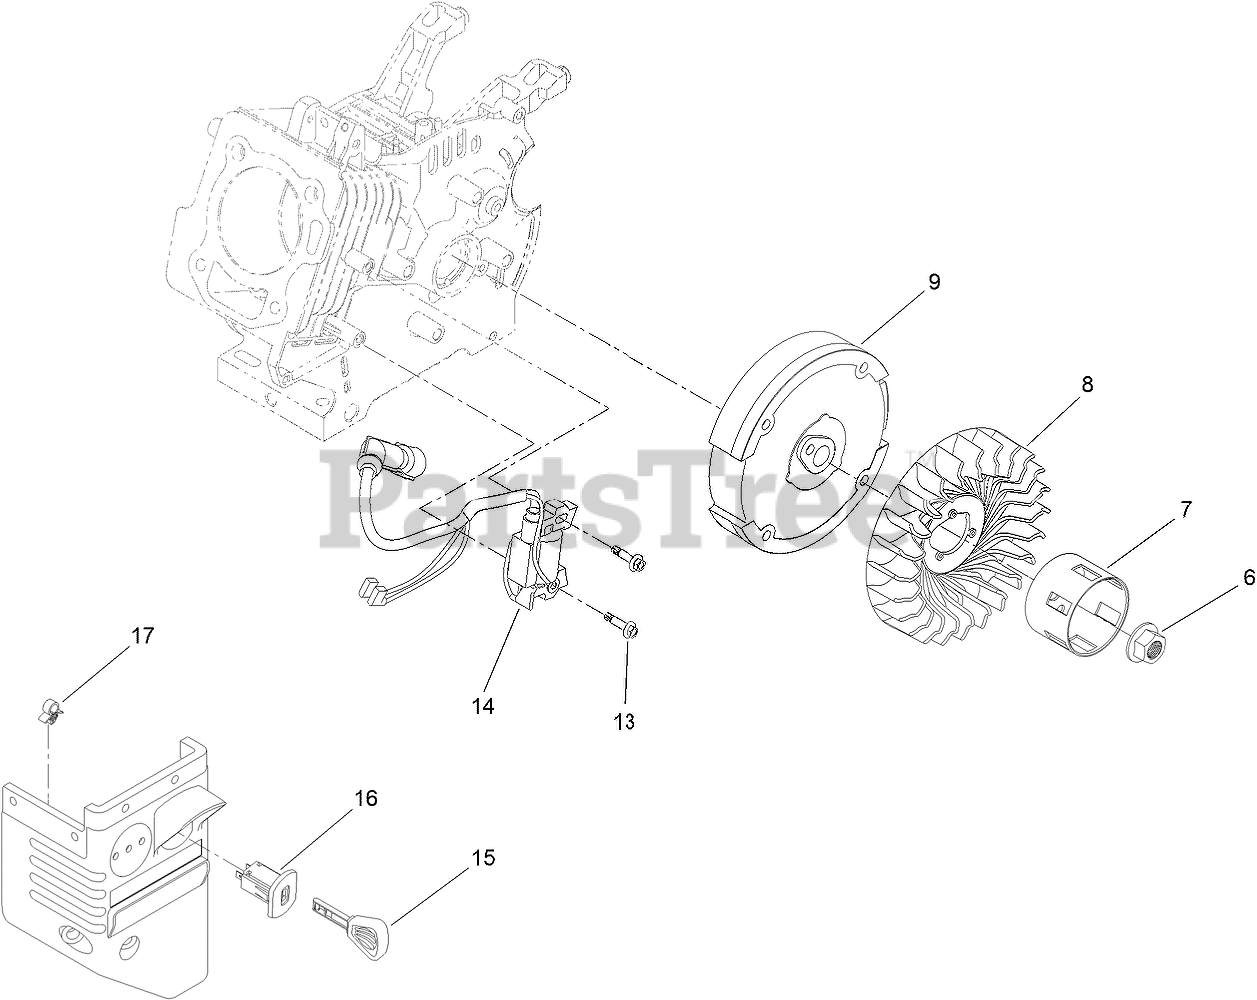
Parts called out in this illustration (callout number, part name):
6	NUT-FLANGE
7	CUP-STARTER
8	FAN-COOLING
9	FLYWHEEL
13	SCREW-HHF
14	IGNITION COIL ASM
16	SWITCH-KEY
